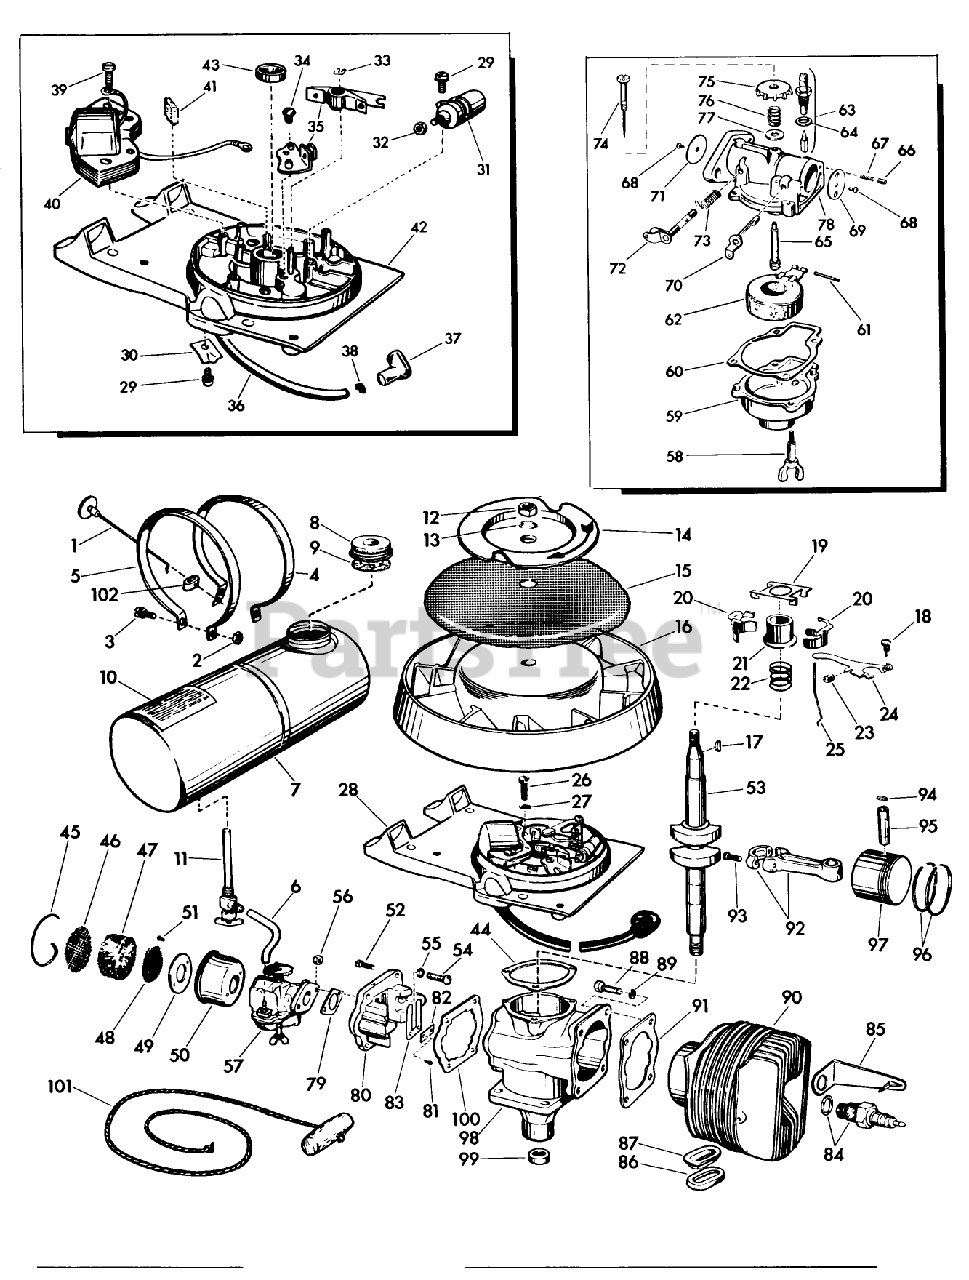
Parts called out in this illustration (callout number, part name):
2	Nut-Tank Strap Screw
3	Screw-Tank Strap
4	Strap-Gas Tank, Left
5	Strap-Gas Tank, Right
8	Gas Cap
11	VALVE&SCREEN SM
14	Pulley-Starter
15	Screen-Flywheel
21	COLLAR S
23	WEAR BLOCK S
25	GOVERNOR ROD S
26	Screw-Pulley to Cap
27	Washer-Lock, Pulley
33	Spring Clip-Breaker Post
35	BREAKER AY. S
37	Cover-Rubber
41	Oiler Wick
44	GASKET S
47	ELEMENT
49	BACK-UP PLATE
52	SCREW S
53	Crankshaft
56	STOP NUT
60	Gasket-Carburetor Body to Float Chamber
68	Screw-Choke Disc
73	SPRING
74	NEEDLE AY. S
76	Spring-Ndl. Adj.
77	Washer-Needle Adjustment
79	GASKET S
82	PLATE-BACKUP, REED
84	Spark Plug
89	Washer-Lock, Cylinder to Crankcase
90	Cylinder Sleeve Assembly
93	Screw-Connecting Rod
96	Ring-Piston
